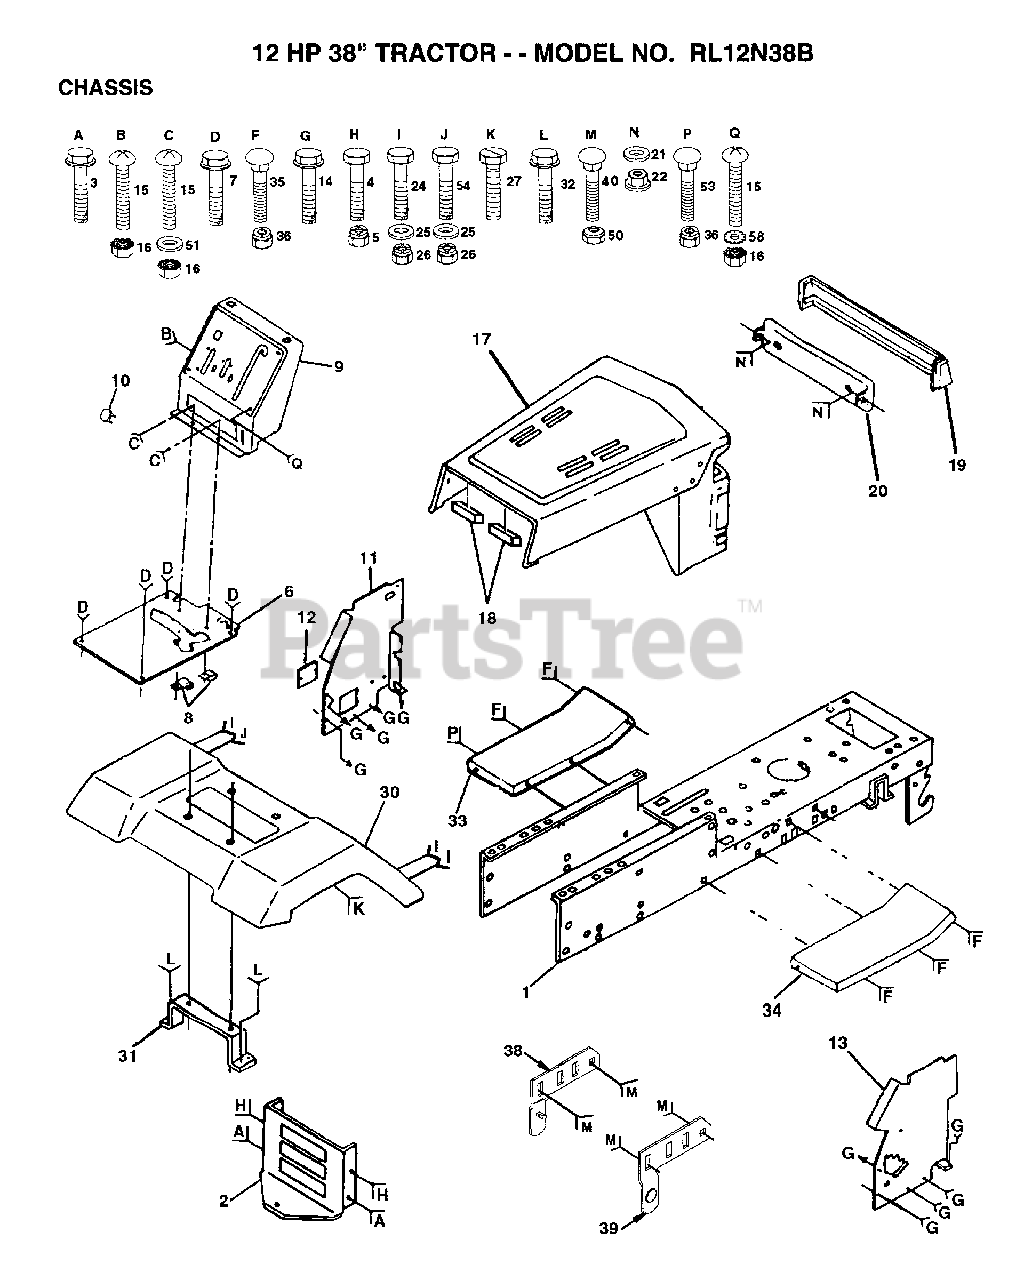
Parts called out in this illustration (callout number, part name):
3	SCREW
6	SADDLE. 5SP
7	SCREW LT
8	CLIP T
10	PLUG BUTTON T
11	PANEL DASH LH
12	COVER ACCESS
14	SCREW LT
15	SCREW
17	HOOD/GRILL ASM
19	LENS SERVICE KIT
21	WASHER PM
22	PAL NUT LT
25	WASHER
27	SCREW LT
31	BRKT FENDER
32	SCREW
33	FOOTREST LH
34	FOOTREST
35	BOLT
38	BRKT ASM PIVOT LH
39	BRKT ASM PIVOT RH
50	NUT
51	WASHER
58	LOCKWASHER
